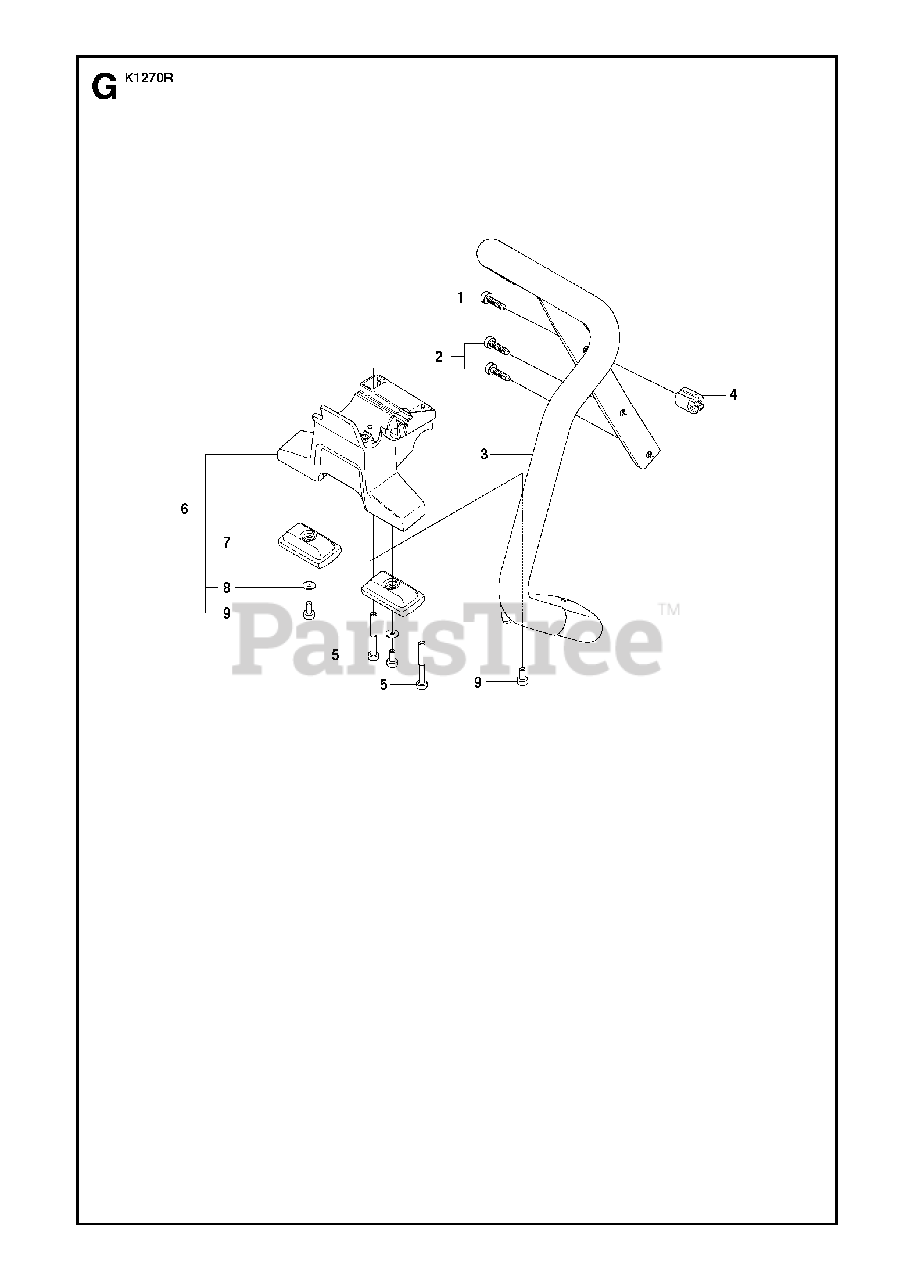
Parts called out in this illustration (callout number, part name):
1	SCREW ITXSCM
2	SCREW ITXSCT
3	HANDLE
4	ANTIVIBRATION ELEMENT
5	SCREW ITXSCM
6	GROUND SUPPORTIncl. 7 - 9
9	SCREW ITXSCT
